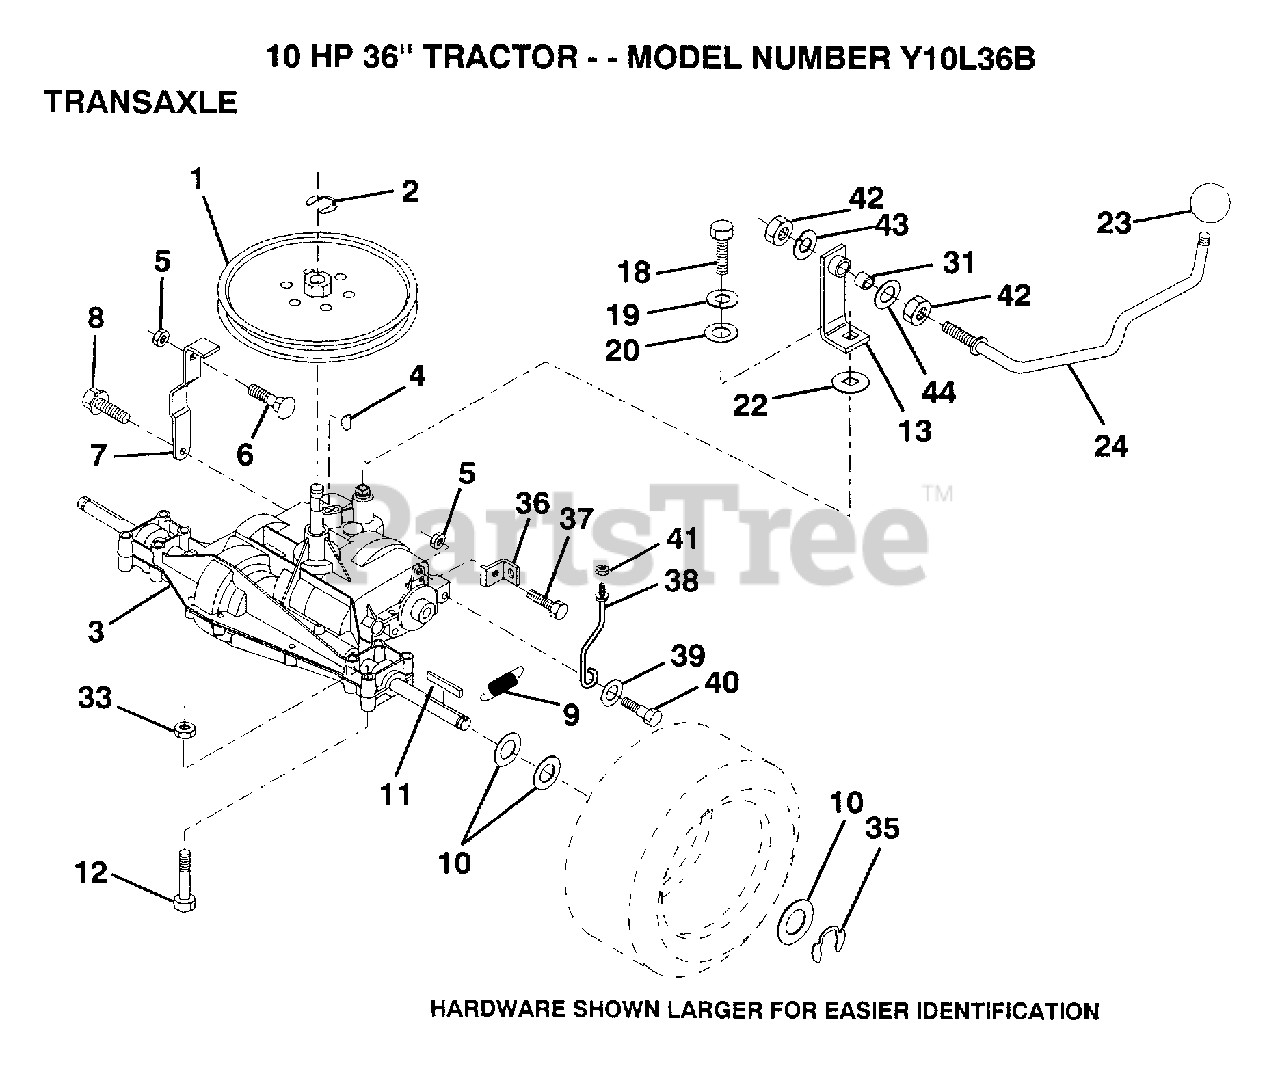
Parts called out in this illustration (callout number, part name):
1	PULLEY
3	TRANSAXLE DANA 5SP
6	BOLT
7	STRAP.TORQUE.LH
8	SCREW
10	WASHER
11	SQUARE KEY
12	BOLT
13	BRACKET.ASM.SHIFT
19	LOCKWASHER
20	WASHER LT
22	WASH-SHFT PLT LT
23	KNOB T (1/2-HOLE)
24	ROD.SHIFT.CNTR.LR
35	E-RING LT
36	BRACKET.BRAKE
37	BOLT
38	KEEPER.BELT.RH
40	BOLT SHD 5/16-18
41	NUT
42	NUT
43	LOCKWASHER
44	WASHER
